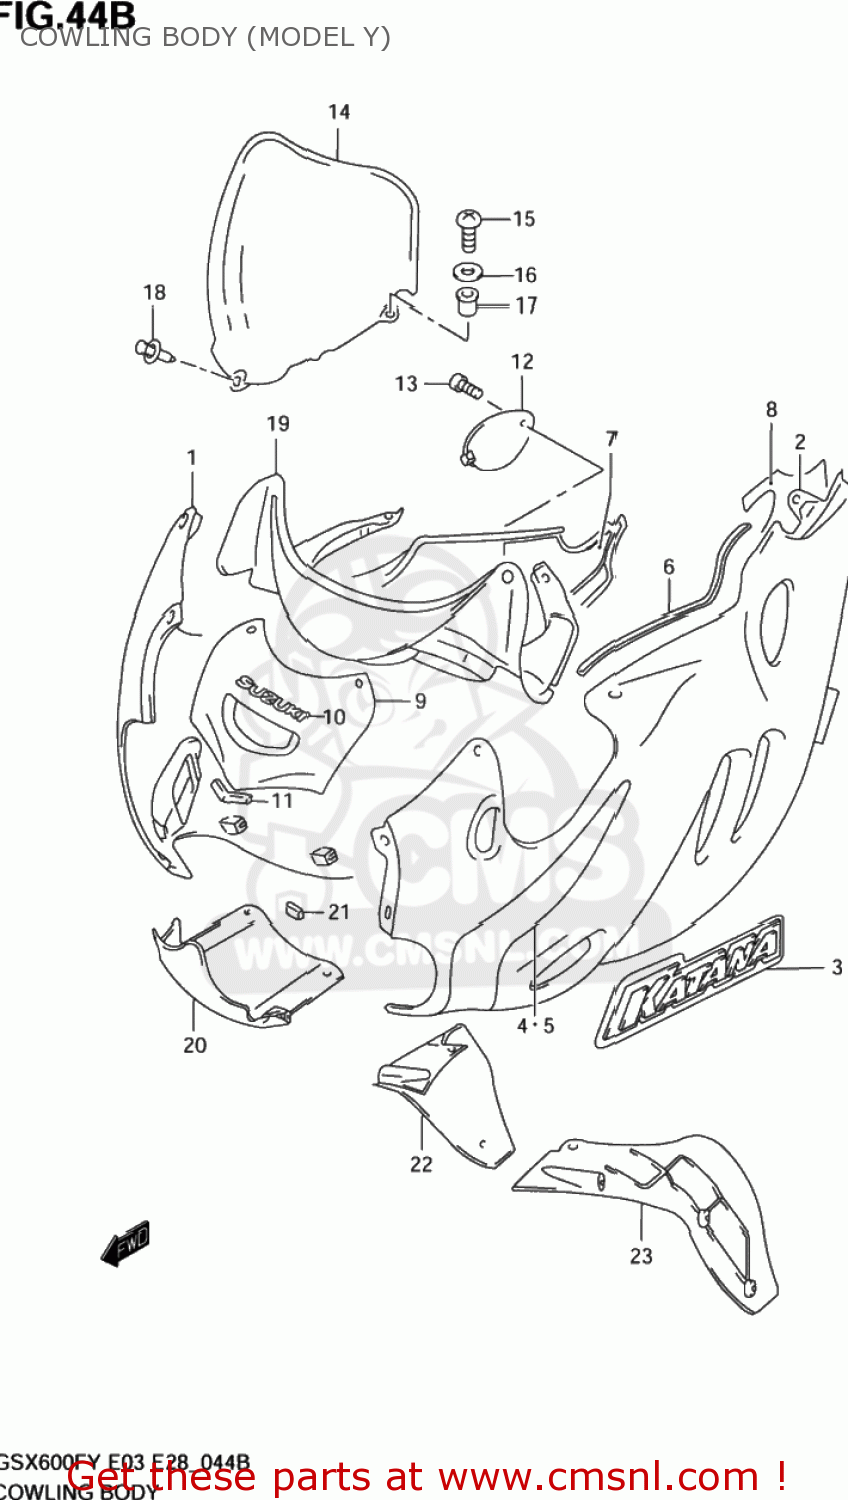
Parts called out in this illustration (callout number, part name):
1	COWLING ASSY,SIDE,R
2	COWLING ASSY,SIDE,L
3	EMBLEM,KATANA
4	TAPE,COWLING SIDE,RIGHT
5	TAPE,COWLING SIDE,LEFT
6	MOLD,COWLING
7	SHIELD,COWLING COVER,R
8	SHIELD,COWLING COVER,L
9	PANEL,COWLING CTR UPR
10	EMBLEM (SUZUKI)
11	CUSHION,CTR PANEL UPR
12	LID,OIL
13	SCREW(6X16)
14	WINDSCREEN
15	SCREW(5X14)
16	WASHER
17	NUT
18	CLIP(BLACK)
19	PANEL,METER
20	PANEL,COWLING CTR LWR
21	CUSHION,CENTER PANEL,LOWER
22	PANEL,COWLING INNER,R
23	PANEL,COWLING INNER,L
